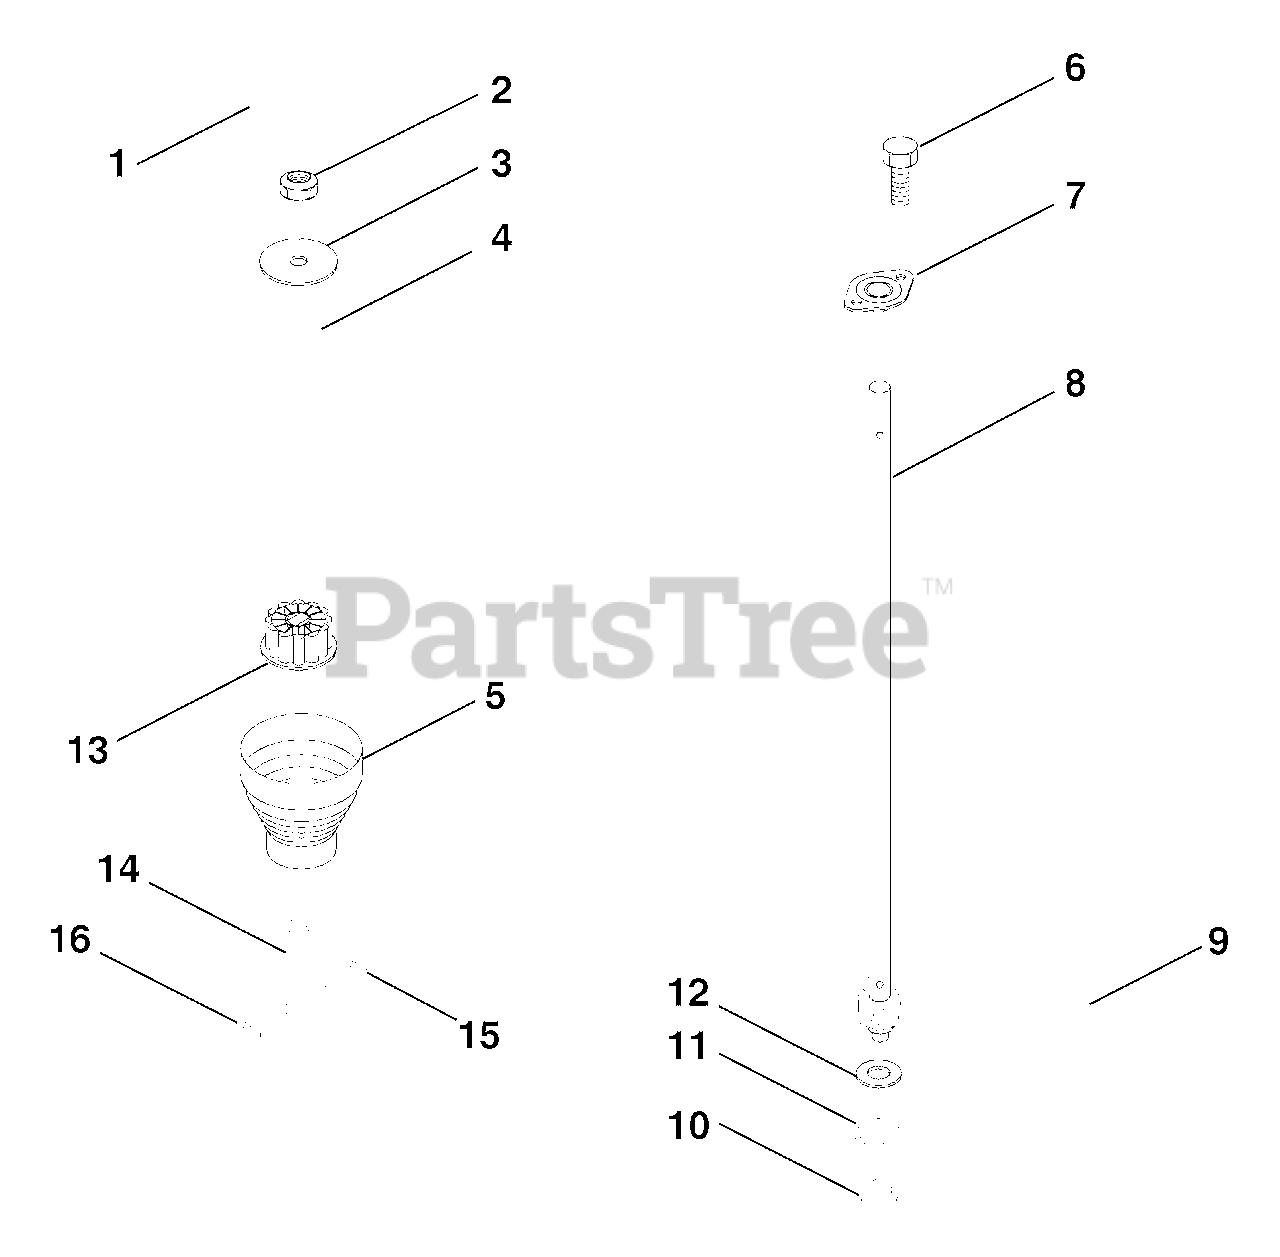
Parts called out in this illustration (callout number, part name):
1	Insert, Wheel, Steering
2	Nut, Lock 3/8-24 UNF
3	Washer 12/32 x 2-3/8 x 8 Ga.
4	Wheel, Steering
5	Sleeve, Steering
6	Screw, Hex #10-16 x 1/2 TY-B
7	Bushing, Steering
8	Shaft, Steering
9	Clip, Steering
10	Bushing, Lower, Steering
11	Ring, Retaining
12	Washer 21/32 x 1 x 16 Ga.
13	Adaptor, Wheel, Steering
14	Extension shaft steering
15	Bolt Fin Hex 5/16-18 UNC x 1-1/4
16	Nut Lock Hex W/Ins. 5/16-18 UNC
